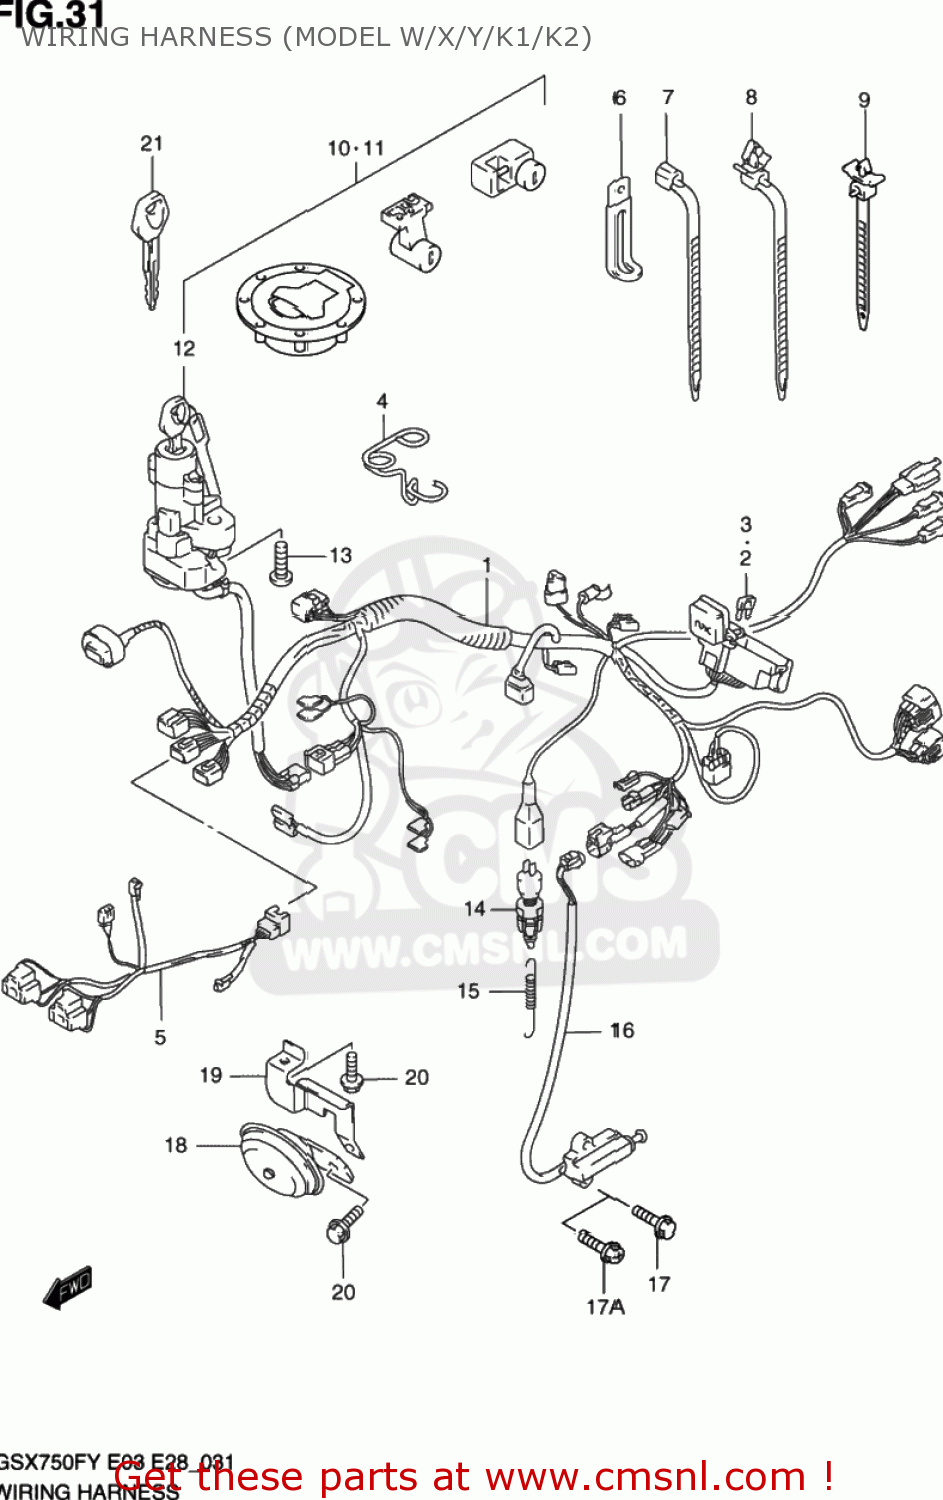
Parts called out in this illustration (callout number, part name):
1	HARNESS,WIRING
2	FUSE(10A)
3	FUSE(15A)
4	GUIDE,WIRING HARNESS
5	HARNESS,WIRING NO.2
6	WIRE,LEAD
7	CLAMP(L:80)
8	CLAMP(L:125)
9	CLAMP
10	LOCK SET
11	LOCK SET
12	LOCK ASSY,STEERING
13	BOLT(8X20)
14	SWITCH ASSY,STOP LAMP
15	SPRING
16	SWITCH ASSY,SIDE STAND
17	BOLT
17A	SCREW
18	HORN ASSY
19	BRACKET,HORN
20	BOLT
21	KEY,BLANK
